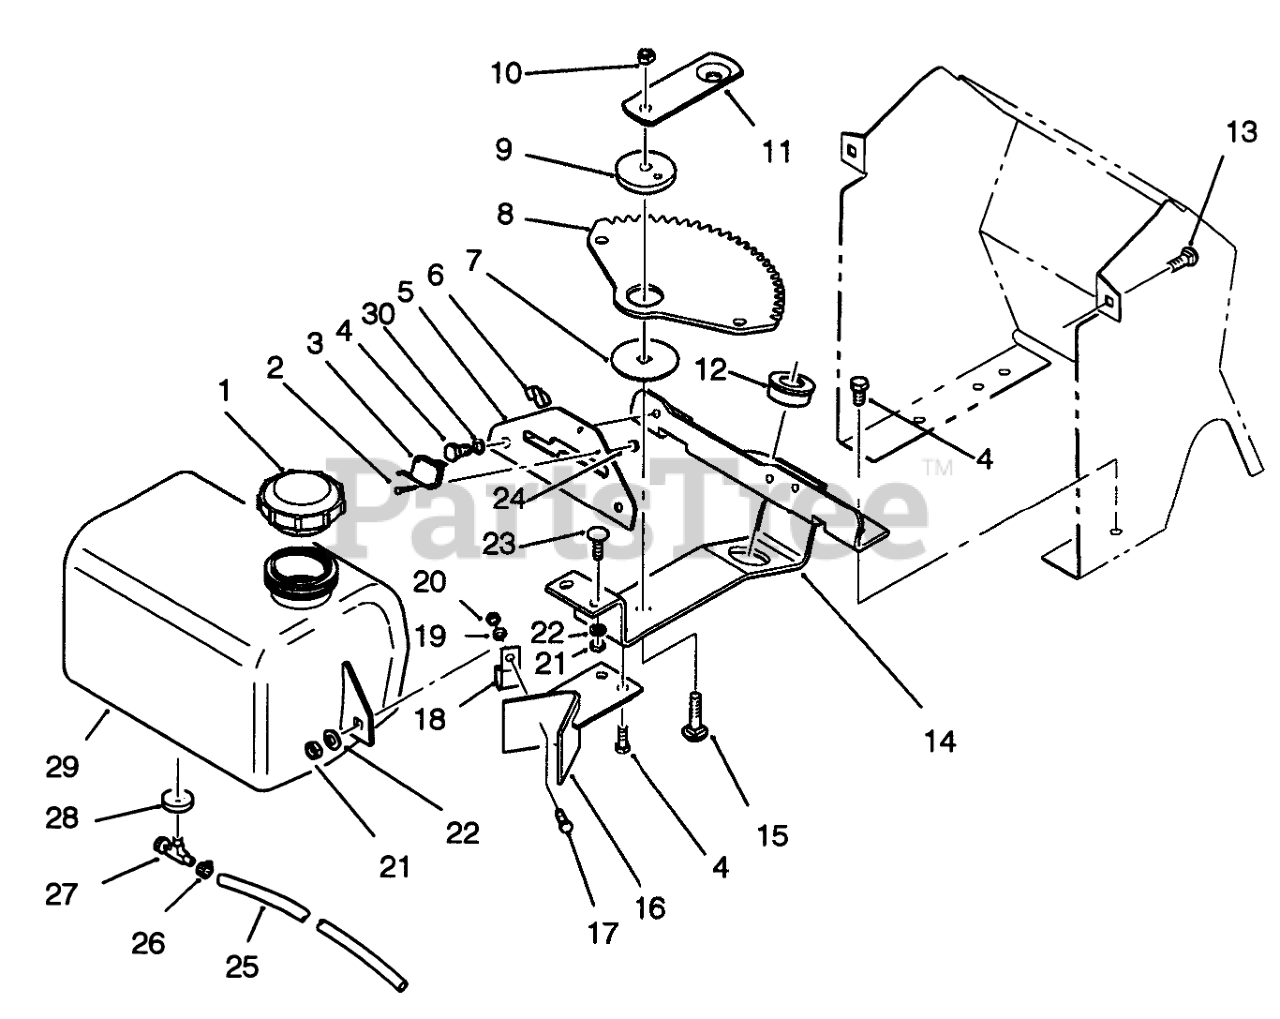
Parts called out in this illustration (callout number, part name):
1	CAP GAS
2	Screw
3	SWITCH - CLUTCH
4	HEX WASH HD SCREW
5	PLATE-SHIFT R
6	CLIP-CABLE
7	WASHER-BEARING
8	GEAR-SECTOR
9	BUSHING
11	Plate
12	BEARING-WHEEL
13	SCREW-CARR
14	STEERING BRKT - W/A R
15	SCREW-CARR
16	Stop
17	Bolt
18	CLIP
20	NUT-LOCK, NI
21	NUT-LOCK, NI
22	WASHER-PLAIN
23	Bolt-Carriage
24	NUT HEX 4-40 ELAST
25	FUEL HOSE(1 FT.6554)
26	CLAMP-HOSE
27	VALVE-FUEL
28	BUSHING
29	ASSY FUEL TANK
